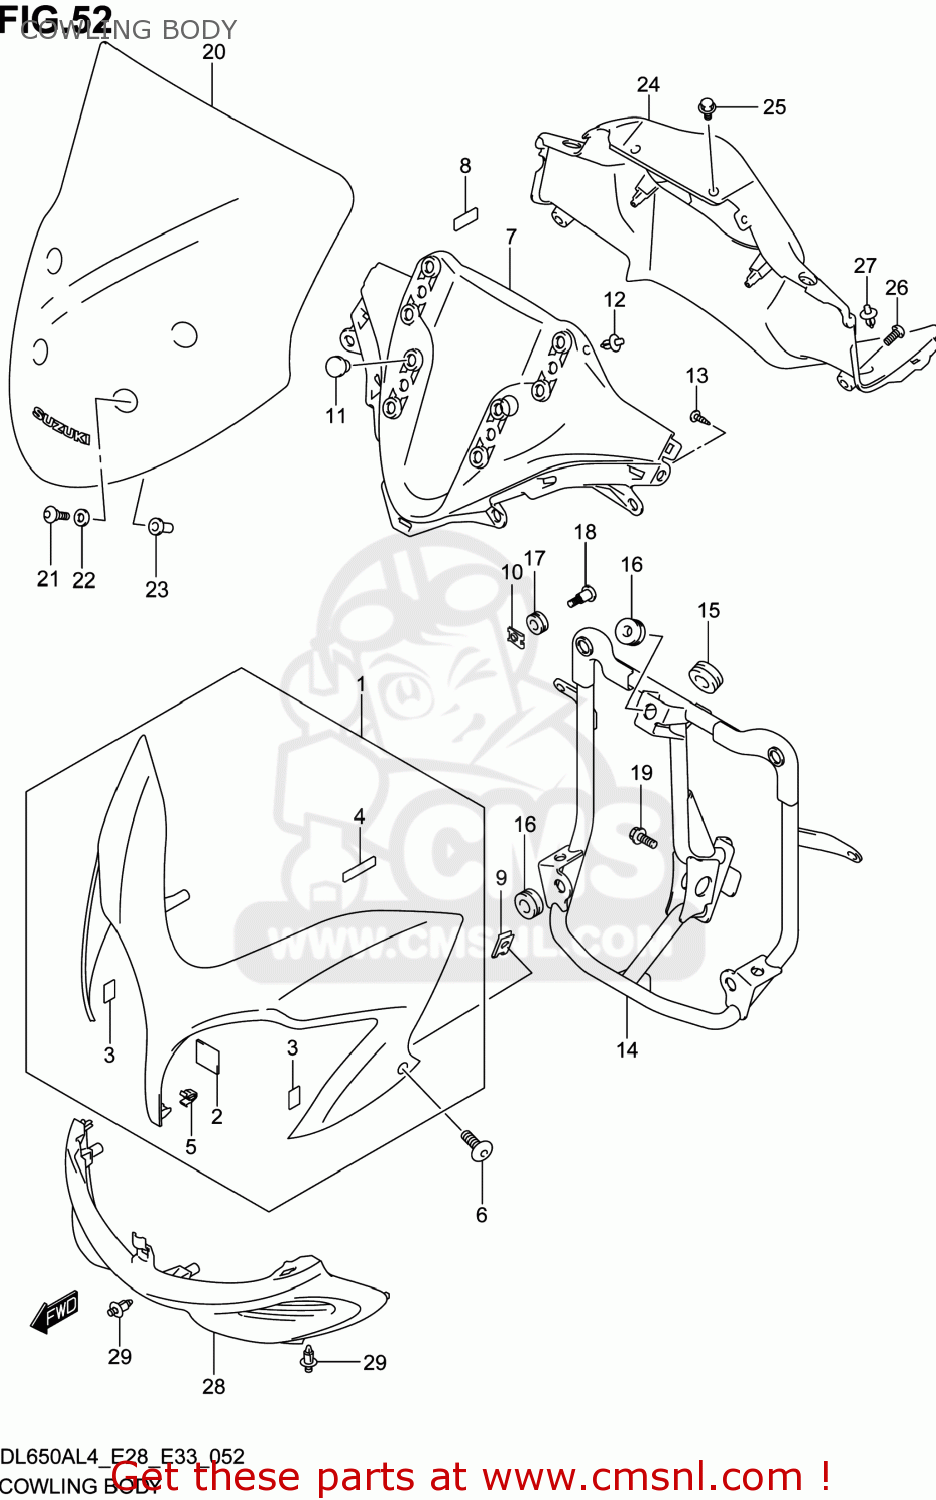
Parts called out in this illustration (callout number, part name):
1	COWLING,BODY(RED)
2	FASTENER
3	FASTENER,COWLING
4	TAPE(6X25X0.13)
5	CLIP
6	SCREW(5X13)
7	PANEL,FR
8	CUSHION
9	NUT
10	NUT
11	CAP(OD:15)
12	CLIP
13	SCREW
14	BRACE,COWLING
15	CUSHION
16	CUSHION
17	CUSHION
18	SCREW(6X20)
19	BOLT
20	WINDSCREEN
21	SCREW(5X18)
22	WASHER(5.5X14X1.2)
23	NUT
24	PANEL,METER
25	BOLT(5X13)
26	SCREW(6X16)
27	CLIP
28	COVER,COWLING INNER
29	CLIP
